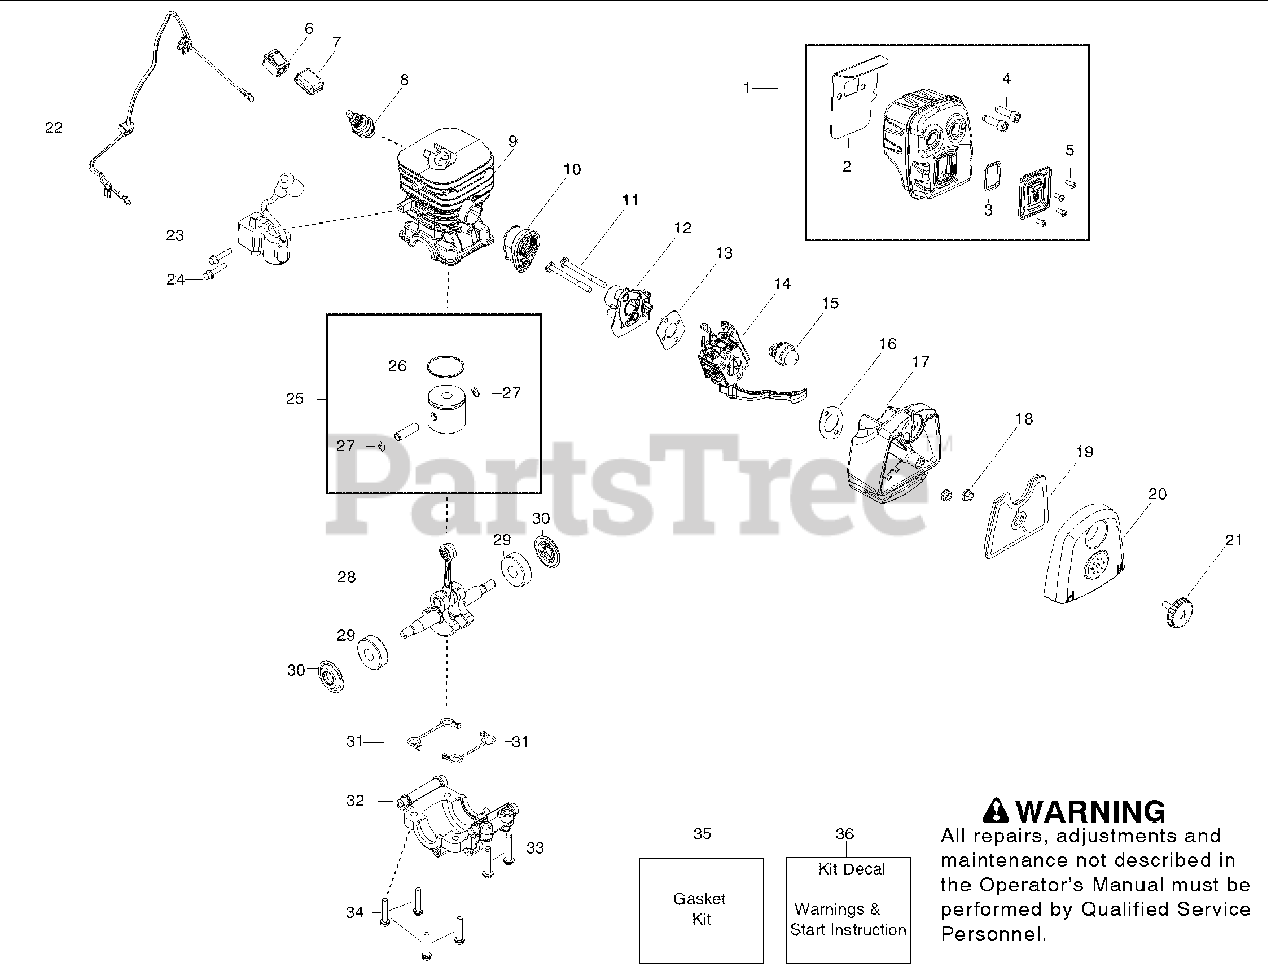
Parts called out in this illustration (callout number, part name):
1	Assy - Muffler
2	Gasket - Muffler
3	Kit - Spark Screen
4	Bolt - Muffler
5	Screw
7	Protector - Switch
8	Accy - Spark Plug
9	Cylinder - Chrome
10	Boot - Carb.
12	Plate - Carb.
13	Gasket - Carb.
14	Kit - Carb.
15	Bulb - Purge
16	Gasket - Airbox
17	Base - Airbox
18	Nut - Carb screw
19	Filter - Air
20	Cover - Airbox
21	Assy - Airbox Knob
22	Assy - Leadwire
23	Module - Ignition
25	Kit - Piston
26	Ring - Piston
27	Retainer - Piston pin
28	Kit - Crankshaft
30	Kit - Crankshaft seal
31	Seal - Cylinder
32	Cap - Bearing
35	Kit - Gasket
36	Kit - Decal
